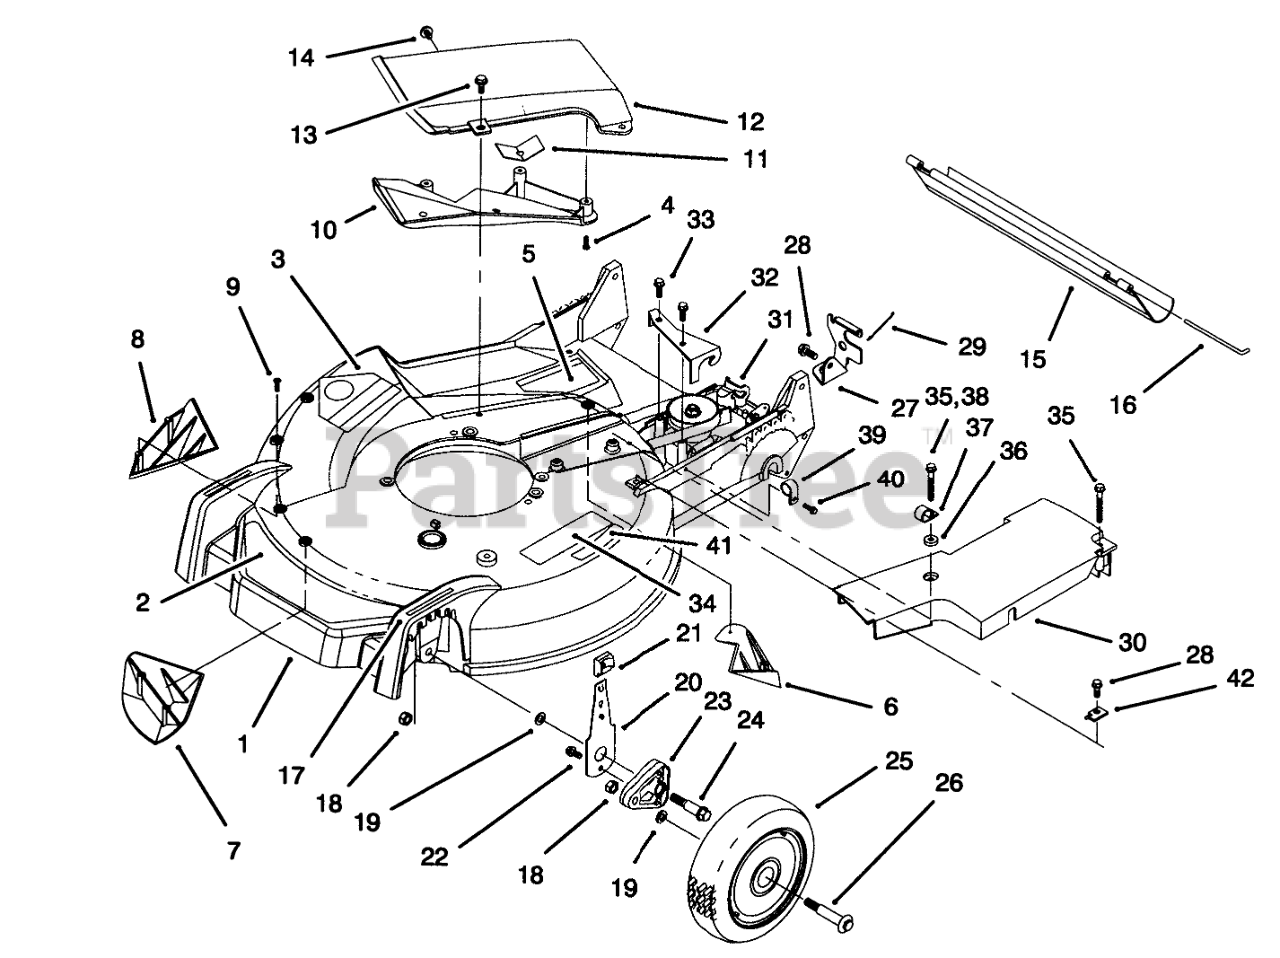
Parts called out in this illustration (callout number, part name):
1	Housing-21" (Incl. Ref. #1, 3, 5-9 pg. 1) (Incl. Ref. #34, & 41 pg. 2)
2	DECAL - DECK
3	DECAL-DANGER
4	Screw-PPH
5	DECAL - DANGER
6	KICKER-REAR
7	KICKER-FRONT
8	KICKER-RH
9	SCREW-PPH
10	Deflector-Recycler
11	Guard-Cover
12	Cover-Recycler (Incl. Ref. #4, 10-11)
13	SCREW-HWH
14	SCREW AND WASHER ASM
15	SHIELD-TRAILING
16	ROD-SHIELD
17	DECAL - HOC
18	NUT-LOCK
19	WASHER
20	FRONT SPRING ARM ASM
21	KNOB-ARM
22	SCREW-HWH
23	ARM-PIVOT, FRONT
24	BOLT-SHOULDER
25	WHEEL AND TIRE ASM
26	BOLT-WHEEL
27	Bracket-Adj. Trac
28	SCREW-HWHTF
29	RETAINER-CABLE
30	BELT COVER
31	GEARCASE ASM
32	Bracket-Guide
33	SCREW-HWHTF
34	DECAL-WARNING
35	SCREW-HHFTF
36	WASHER
37	CLAMP-CABLE
38	SCREW-SPECIAL
39	CLAMP-CABLE
40	SCREW-HWH
41	STEP PAD DECAL
42	CLAMP-CABLE
